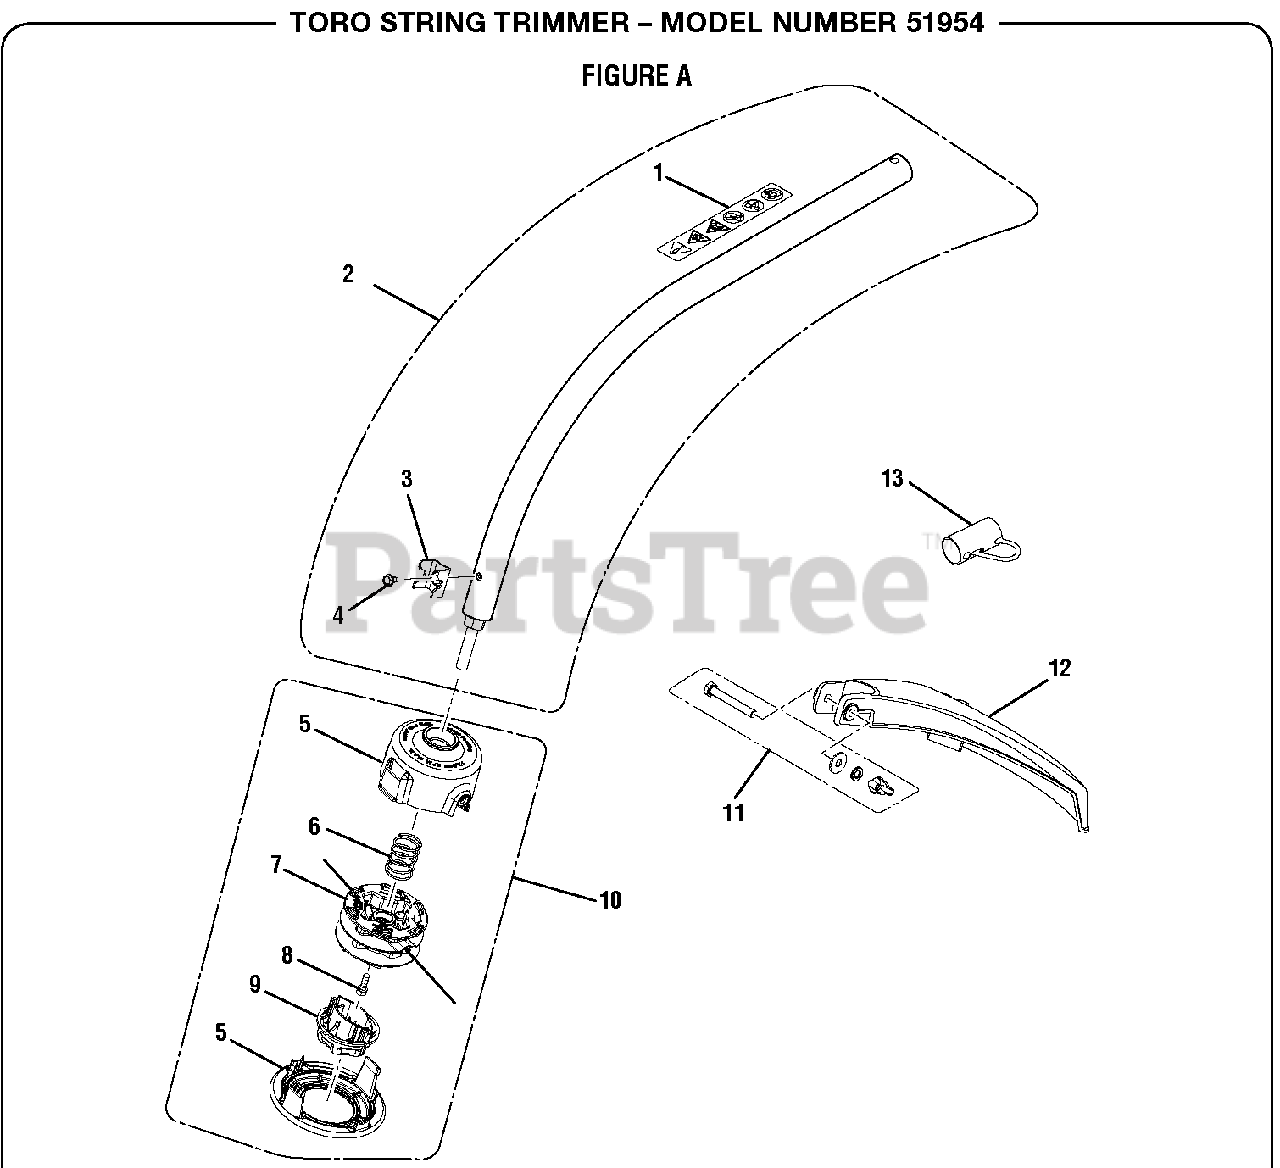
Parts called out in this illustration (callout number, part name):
1	Warning Label
2	Curved Shaft Assembly (Inc. Key Nos. 1, 3 and 4)
4	Screw (#10-32 x 3/8 in., Hex Washer Hd.)
5	Stringhead Housing
6	Compression Spring
7	Spool
8	Bolt (5/16-18 x 1/2 in.)
9	Bump Knob
10	Trimmer Head Assembly (.095) (Inc. Key Nos. 5-9)
11	Fastener Parts Kit
12	Guard (Inc. Key No. 11)
13	Hanger Cap
